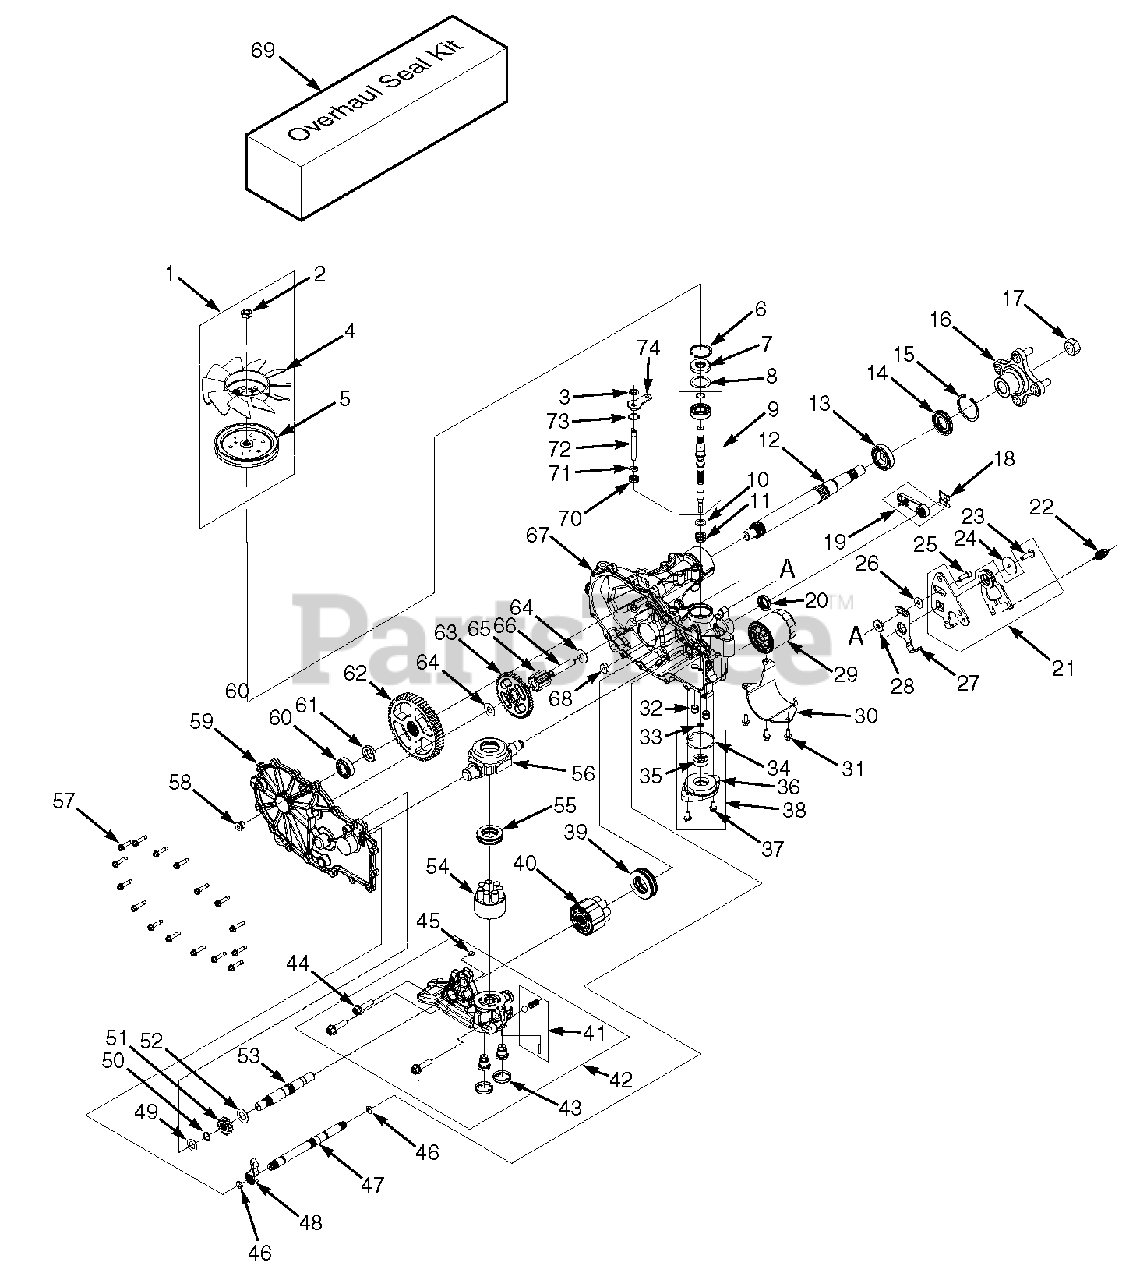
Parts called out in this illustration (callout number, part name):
1	Kit, Fan & Pulley
2	Nut, Elastic Stop 1/2-20
3	Washer, OD Slotted .53 x 1.63 x .06
4	Fan, 7" (10 Blade)
5	Pulley"
6	Ring, Retaining
7	Seal, Lip 17 x 40 x 7
8	Washer, 1.23 x 1.56 x .04
9	Kit, Input Shaft
10	Washer, Flat .59 x .79 x .04
11	Spring, Block
12	Shaft, Axle
13	Bearing, Ball 25.4 x 52 x 15
14	Seal, Lip 1 x 2.049 x .375
15	Ring, Retaining 2.06 Internal
16	Hub, 4-Bolt
17	Nut, Hex Lock 3/4-16
18	Clip, Retaining
19	Handle, Brake Actuating
20	Seal, Lip 12 x 32 x 7
21	Kit, RTN Bi-Directional (Left Side)
21	Kit, RTN Bi-Directional (Right Side)
22	Spring, RTN
23	Bolt, Hex Head Cap Screw 5/16-24 x 1" Patch
24	Washer, .343 x 1.5 x .062
25	Bolt, Hex Head Cap Screw 5/16-24 x 1" Patch
26	Washer, .34 x .88 x .06
27	Arm, Neutral (Right Side)
27	Arm, Neutral (Left Side)
28	Spacer, .320 x 1.005 x .179
29	Filter, Oil
30	Guard, Filter (Right Side)
30	Guard, Filter (Left Side)
31	Screw, Hex Flange 1/4-20 x .625
32	Tibe, Connecting
33	Seal, Lip 8 x 12 x 3-VC
34	O-Ring, -137 x .103 x 2.050
35	Gerotor Assembly (1.9 cc)
36	Cover, Charge Pump
37	Screw, Hex Flange 1/4-20 x .625
38	Kit, Charge Pump
39	Bearing, Thrust
40	Assembly, Cylinger Block
41	Kit, Charge Relief
42	Kit, Center Section (Right Side)
42	Kit, Center Section (Left Side)
43	Seal, Plug 1.250 x .250
44	HFHCS, 3/8-16 X 1-1/2" Patch
45	Plate, By-Pass
46	O-Ring, -111 x .103 x 424
47	Shaft, Brake
48	Pawl, Brake
49	Washer, .63 x 1 x .05
50	Ring, Retaining .625
51	Gear, 13T Steel
52	Washer, .72 x 1.16 x .04
53	Shaft, Motor
54	Assembly, Block 7 Piston
55	Bearing, Thrust
56	Trunnion, Swashplate
57	HFHCS, 1/4-20 x 1-1/8"
58	Plug, 9/16-18
59	Kit, Cover (Right Side)
59	Kit, Cover (Left Side)
60	Bearing, Ball .75 x 40 x 12
61	Spacer, .750 x 1.320 x .257
62	Gear, 54T
63	Gear, 45T
64	Washer, .5 X 1 X .03
65	Gear, 14T Steel
66	Jackshaft Pin
67	Kit, Housing Main (Right Side)
67	Kit, Housing Main (Left Side)
68	Magnet, Ring
69	Seal Kit
70	Seal, Lip .375 x .75 x .25
71	Ring, Retaining .375 External
72	Rod, By-Pass
73	Ring, Retaining .750 Internal
74	Arm, By-Pass
75	Ring, Retaining .375 External
